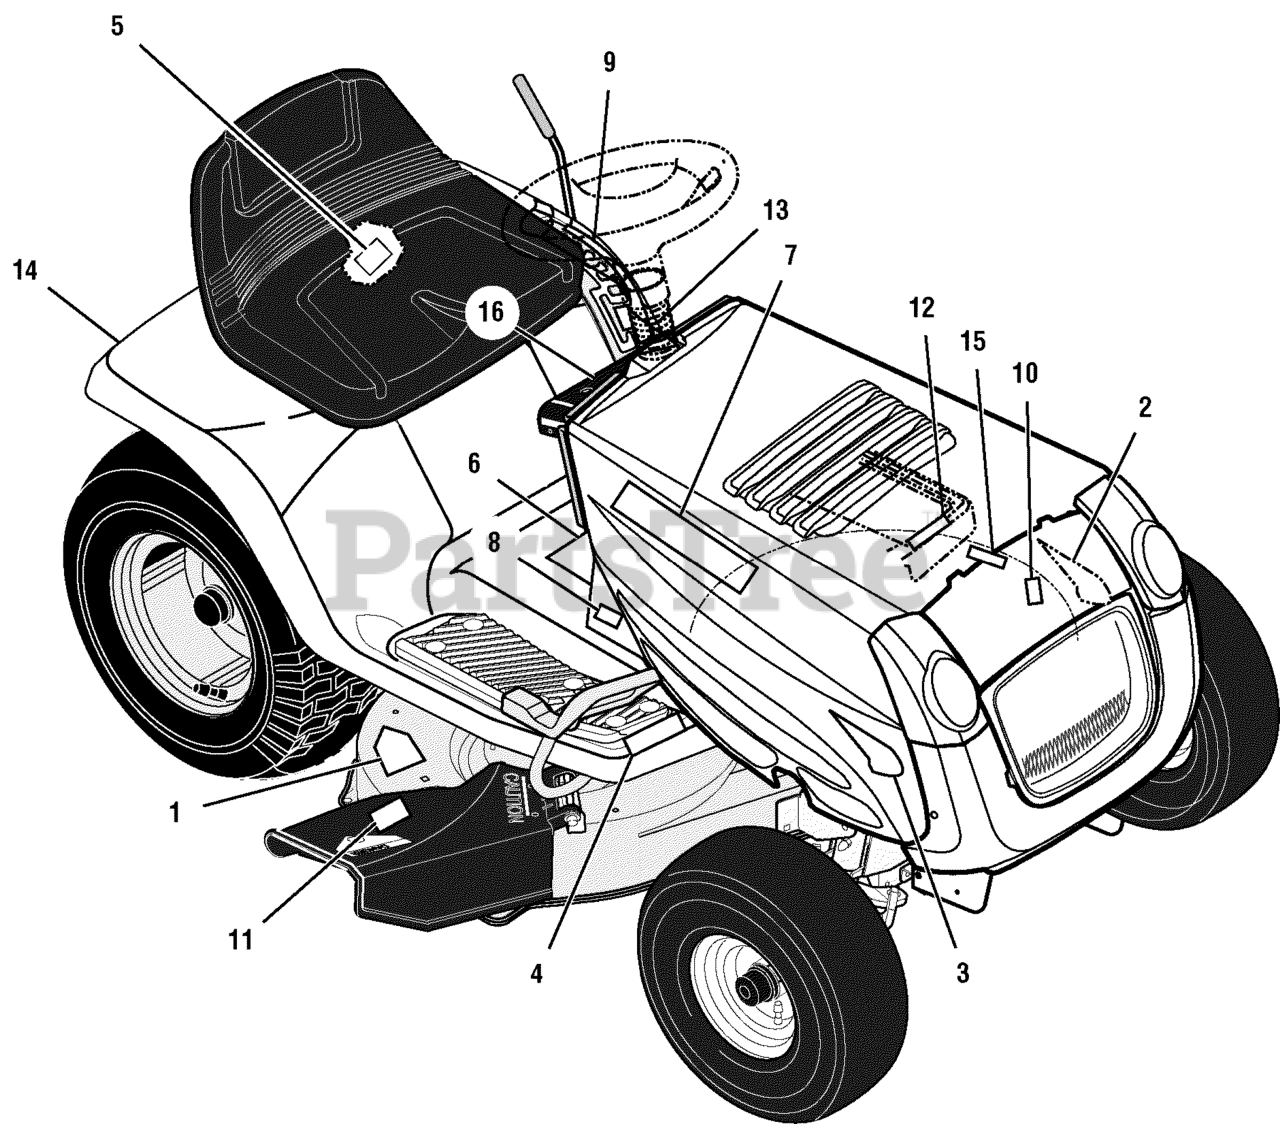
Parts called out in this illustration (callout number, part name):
1	DECAL, ENGLISH CUT FINGER
2	DECAL, 15.5/40 LH
3	DECAL, 15.5/40 RH
4	DECAL, V3-DC-5X2 HYDRO DRIVE
5	DECAL, HYDRO RELEASE DOM
6	DECAL, WARNING
7	DECAL, SENTINEL BY MUR R & L
8	DECAL, BRIGGS LOGO
9	DECAL, 1/6 HGT ADJUST LIFT SMSD
10	DECAL, NO STEP LH HSNG
11	DECAL, NO STEP CHUTE
12	DECAL, BRAKE/PARK BRAKE
13	DECAL, DECK LEVEL POS/ONLY
14	DECAL, DRAWBAR WARNING PICT
15	DECAL, 3 WAY
16	DECAL, IGNITION SWITCH (NMR)
